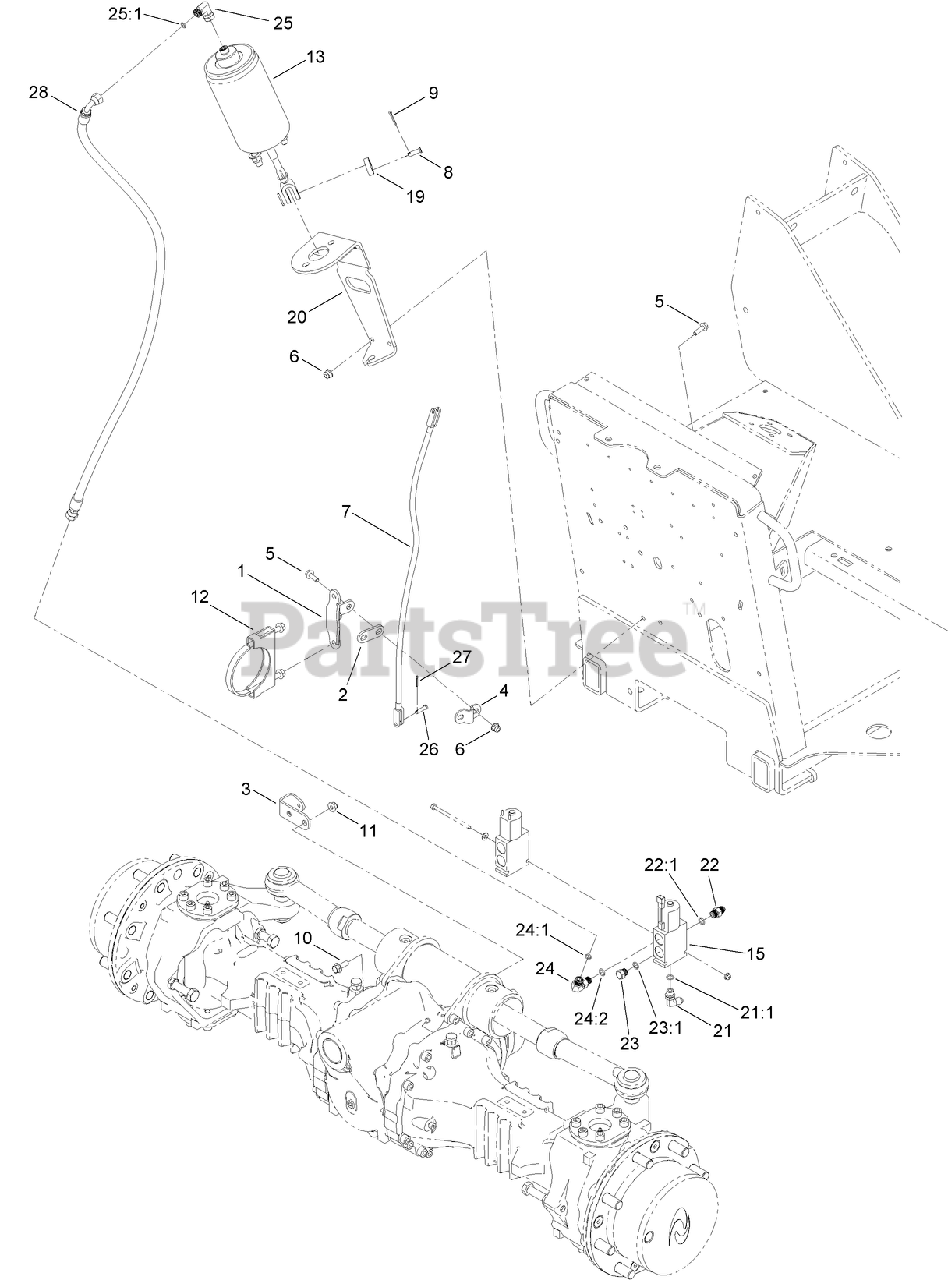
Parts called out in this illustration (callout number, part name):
1	BRACKET-CABLE, PARKING BRAKE
3	PLATE-MOUNT, PARKING BRAKE
4	CLAMP-Cable
5	SCREW-HH
6	NUT-TORQUE, PREVAILING
7	BRAKE CABLE ASM
8	PIN-CLEVIS
9	PIN-COTTER
10	SCREW-HHF
11	NUT-HF, NI
12	CLAMP-MUFFLER
13	HYD CYLINDER RELEASE ASM
15	SOLENOID VALVE ASM
19	LINK-CABLE, PARKING BRAKE
20	MOUNT-BRAKE, PARKING
21	FITTING-ELBOW, 90 DEG
21:1	O-RING
22	FITTING-STRAIGHT
22:1	O-RING
23	PLUG-HH
23:1	O-RING
24	FITTING-ELBOW, 90 DEG
24:1	O-RING
24:2	O-RING
25	FITTING-HYD, 90 DEG
25:1	O-RING
26	PIN-CLEVIS
27	PIN-COTTER
28	HOSE ASM
